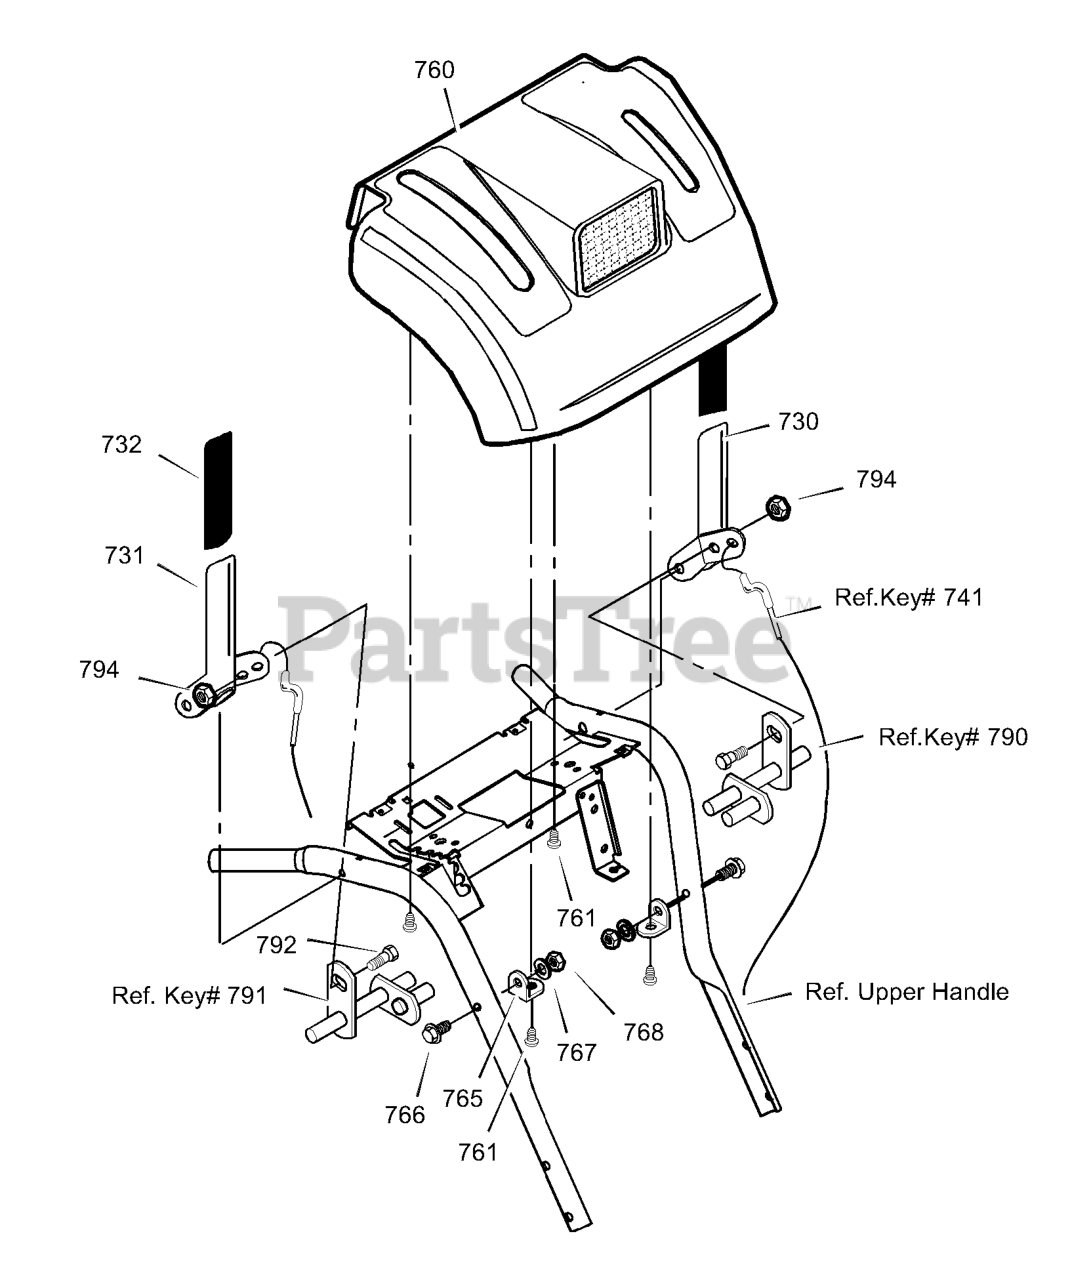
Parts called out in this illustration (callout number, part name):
730	CLUTCH HANDLE LH
731	CLUTCH HANDLE RH
732	GRIP, CLUTCH LEVER
760	PANEL, CONTROL
761	SCREW, 10 X .62
765	BRACKET, PANEL
766	SCREW, 5/16-18 x 1.75
767	WASHER, HVSPTLK
768	NUT, 5/16-18
792	BOLT, 1/4-20 X .50
794	NUT, 1/4-20
